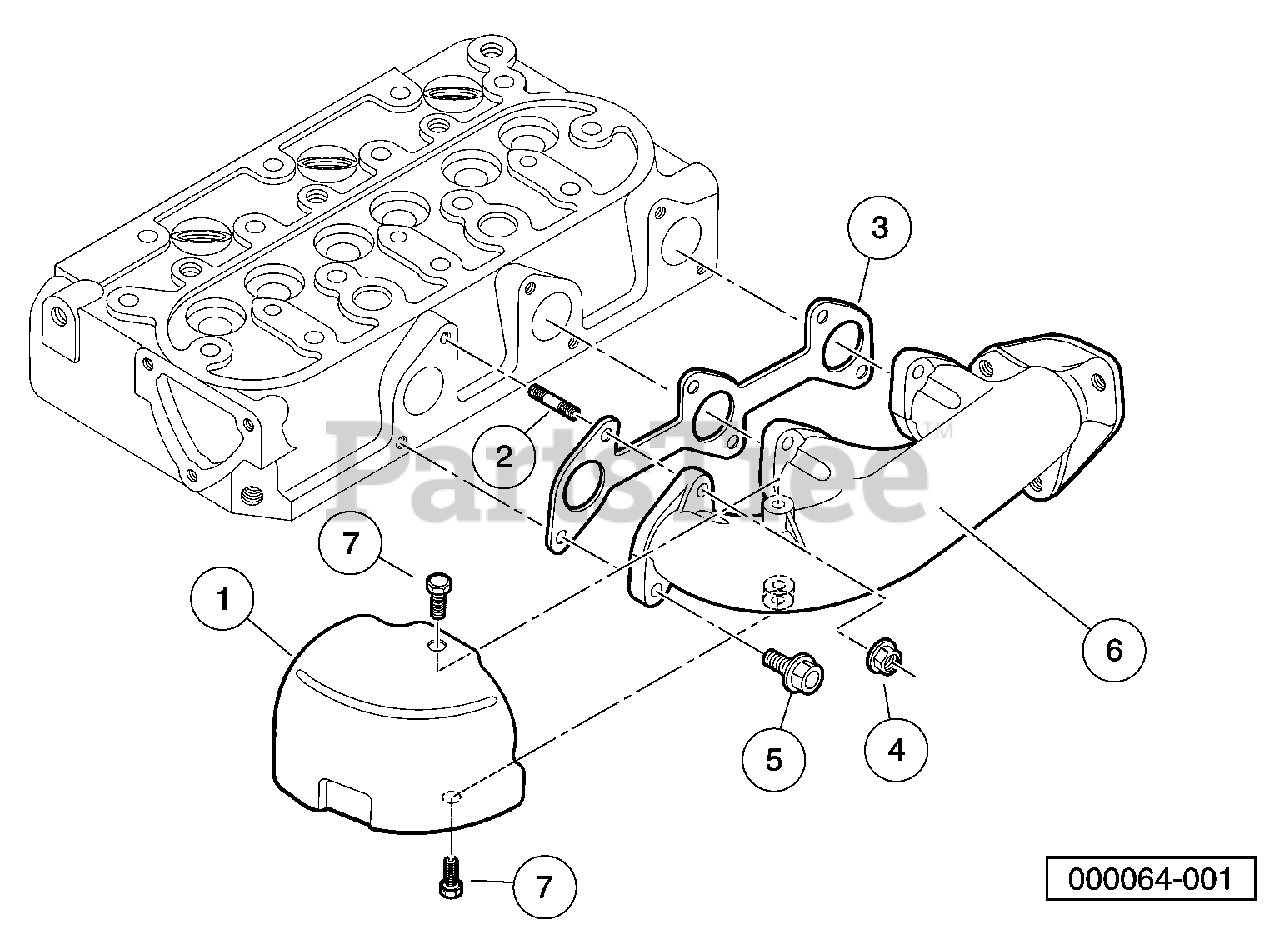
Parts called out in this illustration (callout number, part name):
1	Cover, Heat Proof
2	Stud, M6 X 26
3	Gasket, Ex-manifold
4	Nut, Flange, M6, Ubs
5	Bolt, Flange Head, M6 X 1 X 16
6	Manifold, Exhaust, D722
7	Bolt, D722, Exhst Manfld Cover
